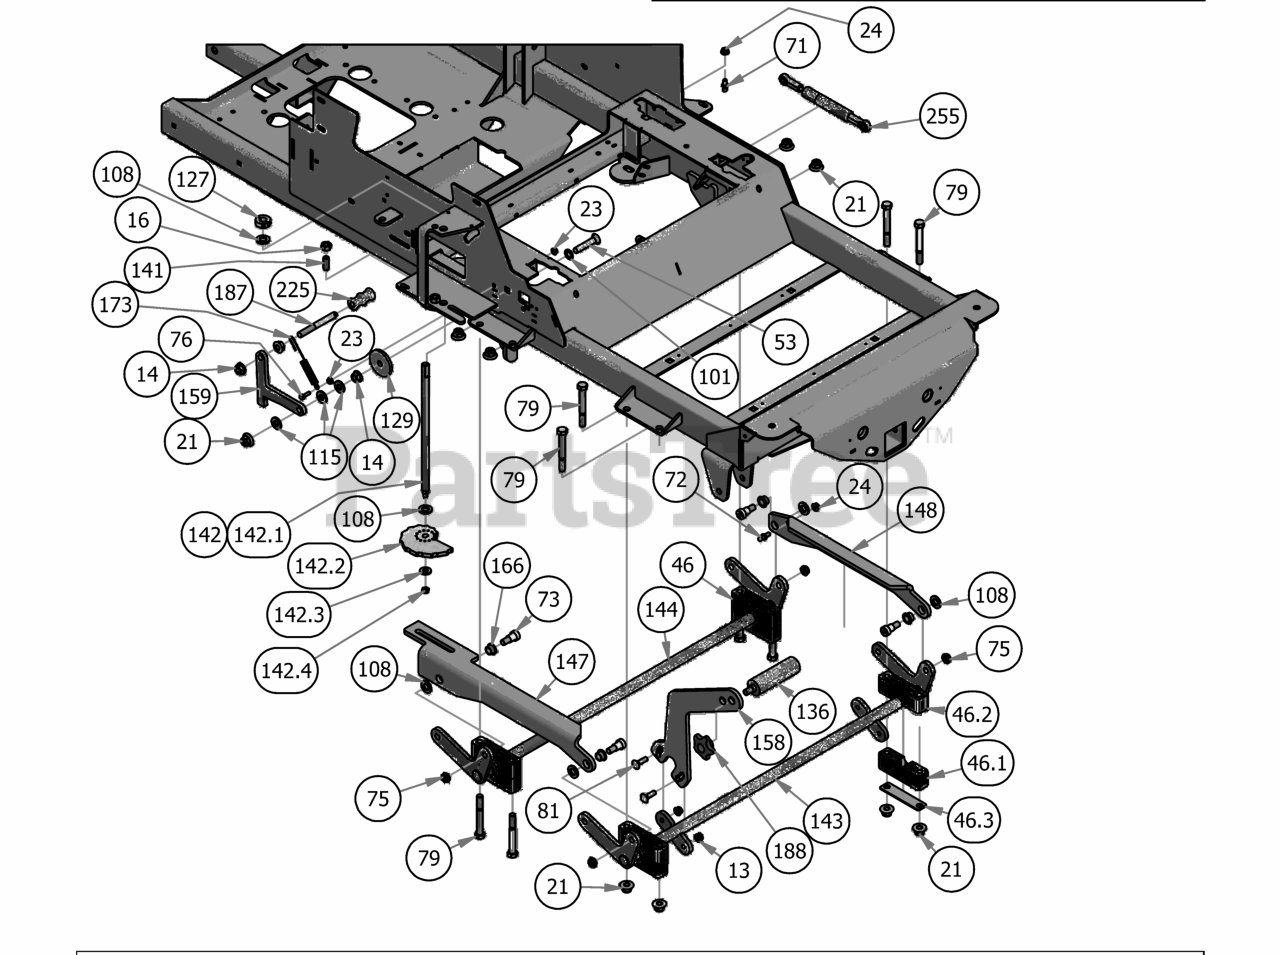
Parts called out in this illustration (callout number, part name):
13	3/8" Nylock Flange Nut
14	1/2" Flange Nut
16	1/2" Hex Nut
21	1/2-13 Nylon Flange Nut
23	1/4-20 Hex Flange Nuts Zinc w/Serrations
24	5/16" Flange Nut
46	Pillow Block Assembly
46.1	Two Piece Pillow Block (Male)
46.2	Two Piece Pillow Block (Female)
46.3	Two Piece Pillow Block Strap
53	1/2 x 2-1/2 Carriage Bolt
71	10mm Damper Ball Stud-Steering
72	10mm Damper Ball Stud-XP Linkage
73	5/8'' x 5/8'' Shoulder Bolt
75	1/2" Nylcock Nut (1/2 Jam)
76	1/4-20 x 1-1/4 GR 5 Hex Bolt
79	1/2" x 4" Bolt (Grade 8)
81	3/8" x 1 1/4" Carriage Bolt
101	.517 Square Hole Round Washer
108	.630 ID Plastic Washer
115	.505 Nylon Spacer
127	5/8" Split Collar
129	MZ Deck Idler Spacer
136	Knurled Pedal
141	Dial Rod Plunger
142	2019 Outlaw Gen2 Deck Height Dial Rod Assy
142.1	2019 Outlaw Gen2 Dial Rod
142.2	2019 Deck Height Cam
142.3	3/8" Flat Washer
142.4	3/8-24 Nylon Insert jam locknut
143	2019 Outlaw Actuator - Front
144	2019 Outlaw Actuator - Rear
147	2019 Actuator Linkage - Right
148	2019 Actuator Linkage - Left
158	Foot Lift Upright Lever
159	2019 Outlaw Deck Travel Lock
166	Bronze Bushing - SF - 2024-8
173	Brake Spring
187	Seat Braket Pin
188	Foot Pedal Knob 1/2-13
225	Travel Lock Rubber Grip
230	2019 Horizontal Diesel Frame
255	250lb Gas Spring - 61" Deck
